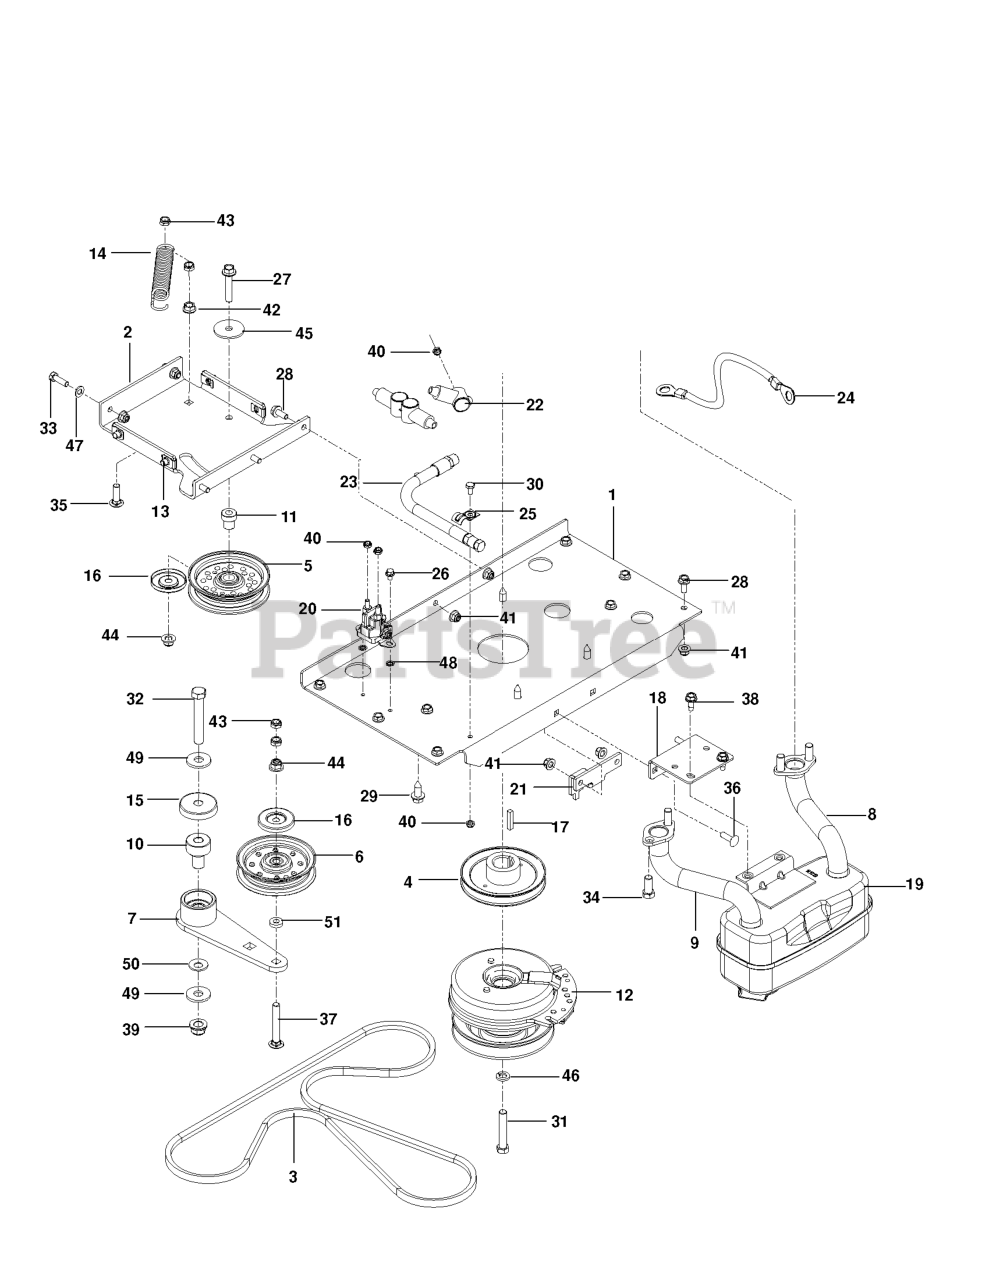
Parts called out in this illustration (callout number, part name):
1	PLATE, ENGINE, BLK
2	PLATE, IDLER, BLK
3	BELT, HYDRO, 3400
4	PULLEY, V, 1.125 BORE
5	IDLER PULLEY
6	FLAT IDLER PULLEY
7	ARM, IDLER, STEEL, W/BGS
8	PIPE.EXHAUST.RH.CV18/20
9	PIPE.EXHAUST.LH.CV18/20
10	PIVOT, BEARING
11	PIVOT, IDLER
12	CLUTCH 200 FT LB
13	U-CLIP 5/16-18 NUT RETAINER
14	SPRING, PUMP
15	SHIELD, DUST
16	DUST SHIELD
17	KEY, 1/4 SQ X 1 1/4
18	BRKT, MUFFLER, BLK
19	MUFFLER ASM TWIN
21	STOP, CLUTCH, BLACK
23	HOSE.ASSEMBLY.OIL.DRAIN
24	CABLE POSITIVE
26	HWST 1/4C X 3/8
27	HHFS 3/8-16 X 2.0 GD 5
28	HHFS 5/16-18 X 3/4
29	HHFS 3/8-16 X 1.0 THD FORMING
30	HCS 1/4-20.
31	CLUTCH BOLT7/16-20X2.5 GR596HR
32	HCS 1/2C X 3 1/4
33	HCS 5/16C X 1
34	HCS 5/16C X 3/4
35	RHSNB 3/8-16 X 1-1/4
36	RHSSNB 5/16C X 1.0
37	RHSNB 3/8-16 X 2.75
38	BOLT 5/16-18 X 3/4
39	NUT, 1/2-13 HEX FLG NYLOC ZD
40	JAM NUT 1/4C (2 2 PW01)
41	5/16-18 NYLOC FLANGE NUT
42	NUT 3/8C WHIZ
43	NUT HEX 3/8-16 NYLON, THIN
44	NUT 3/8-16 HEX FLG NYLOC ZD
45	WASHER, 3/8 SPEC
46	WASHER 7/16 LOCK
47	FLAT WASHER 5/16 SAE
48	WASHER 1/4 INT TOOTH
49	WASH USS FLAT 1/2
50	CONTACT BELLSPR 1/2
51	WASHER 3/8 X 3/4 X .187 TK
